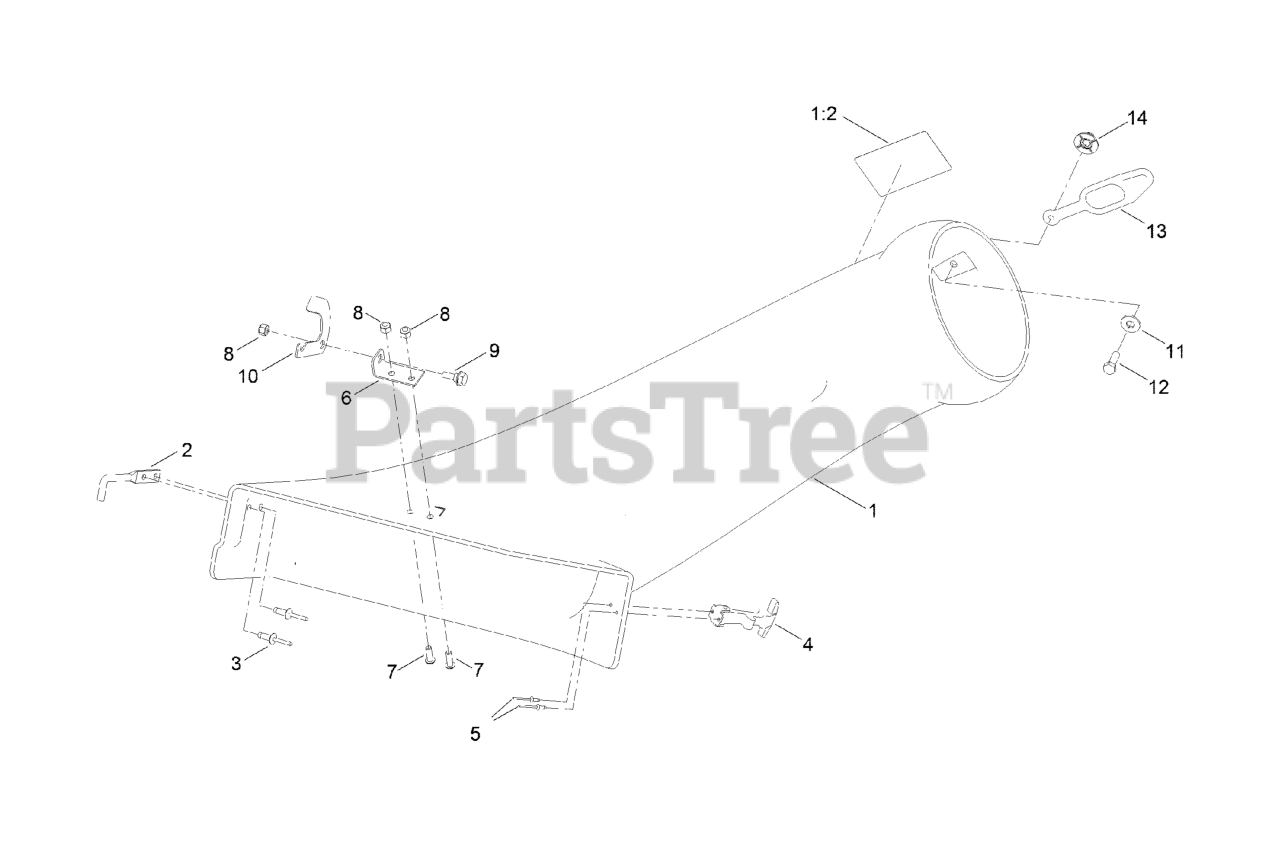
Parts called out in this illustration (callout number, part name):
1	42 In Bagger Boot ASM
1:2	DECAL-DANGER
2	HOOK-BOOT
3	RIVET-BLIND
4	HANDLE ASM
5	RIVET-POP
6	Plate-Pivot, Cz
7	SCREW-HSBH
8	NUT-HEX
9	SCREW-SHOULDER, HHF
10	Plate-Latch
11	WASHER-FLAT
12	SCREW-HH
13	RETAINER-DUCT
14	NUT-IMPELLER
